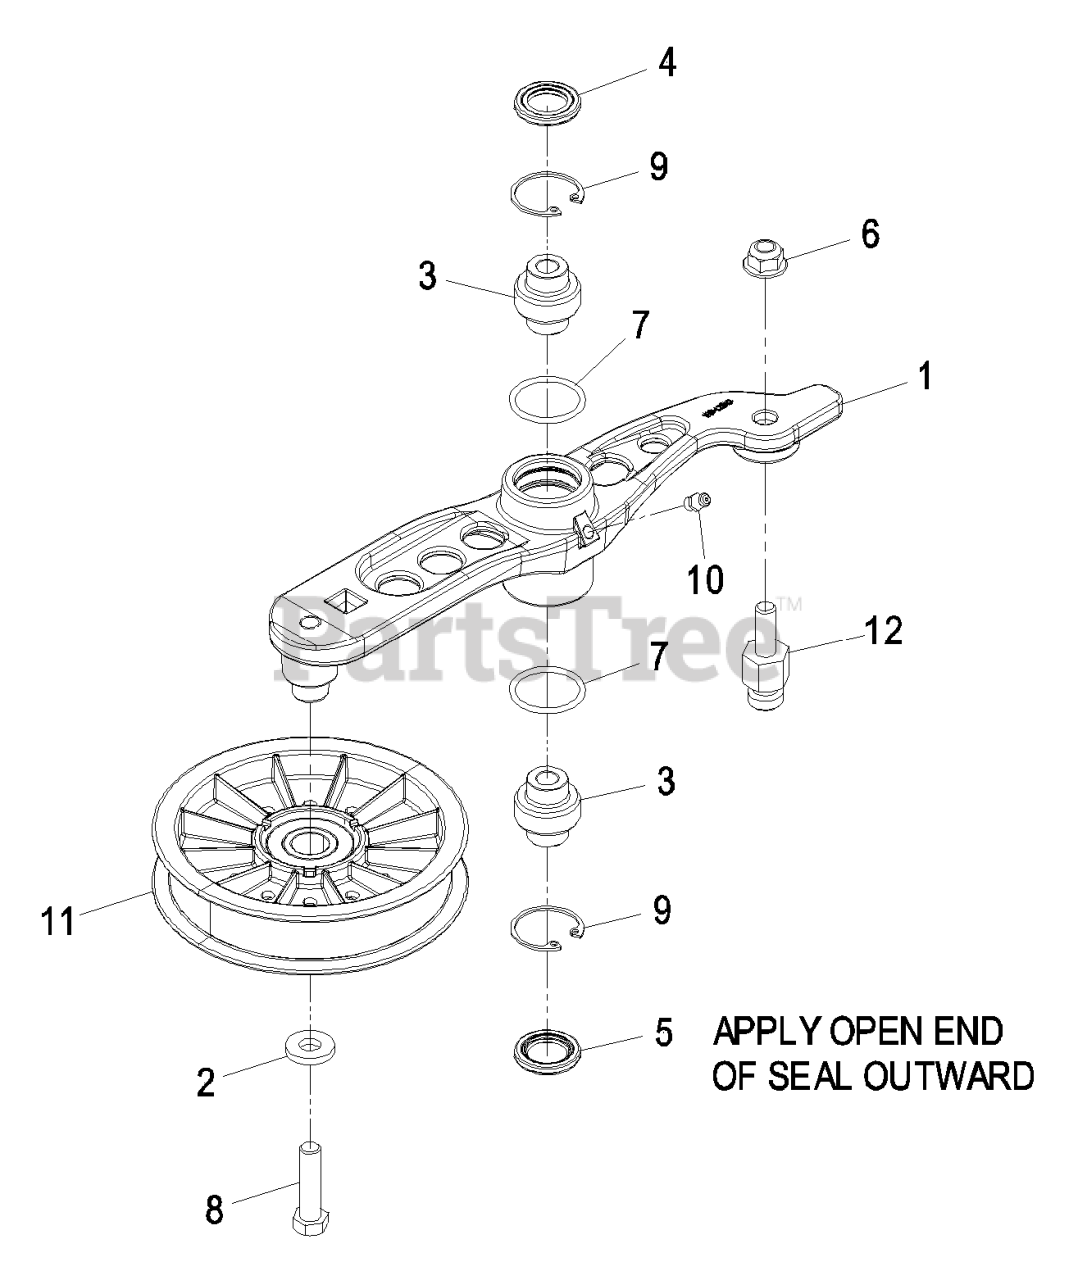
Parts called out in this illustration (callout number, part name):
3	BEARING-SPHERICAL
4	SEAL-LIP, DOUBLE
5	SEAL-LIP, SINGLE
6	NUT-HF, NI
8	SCREW-HH
9	RING-SNAP
10	FITTING-GREASE
11	PULLEY-IDLER
